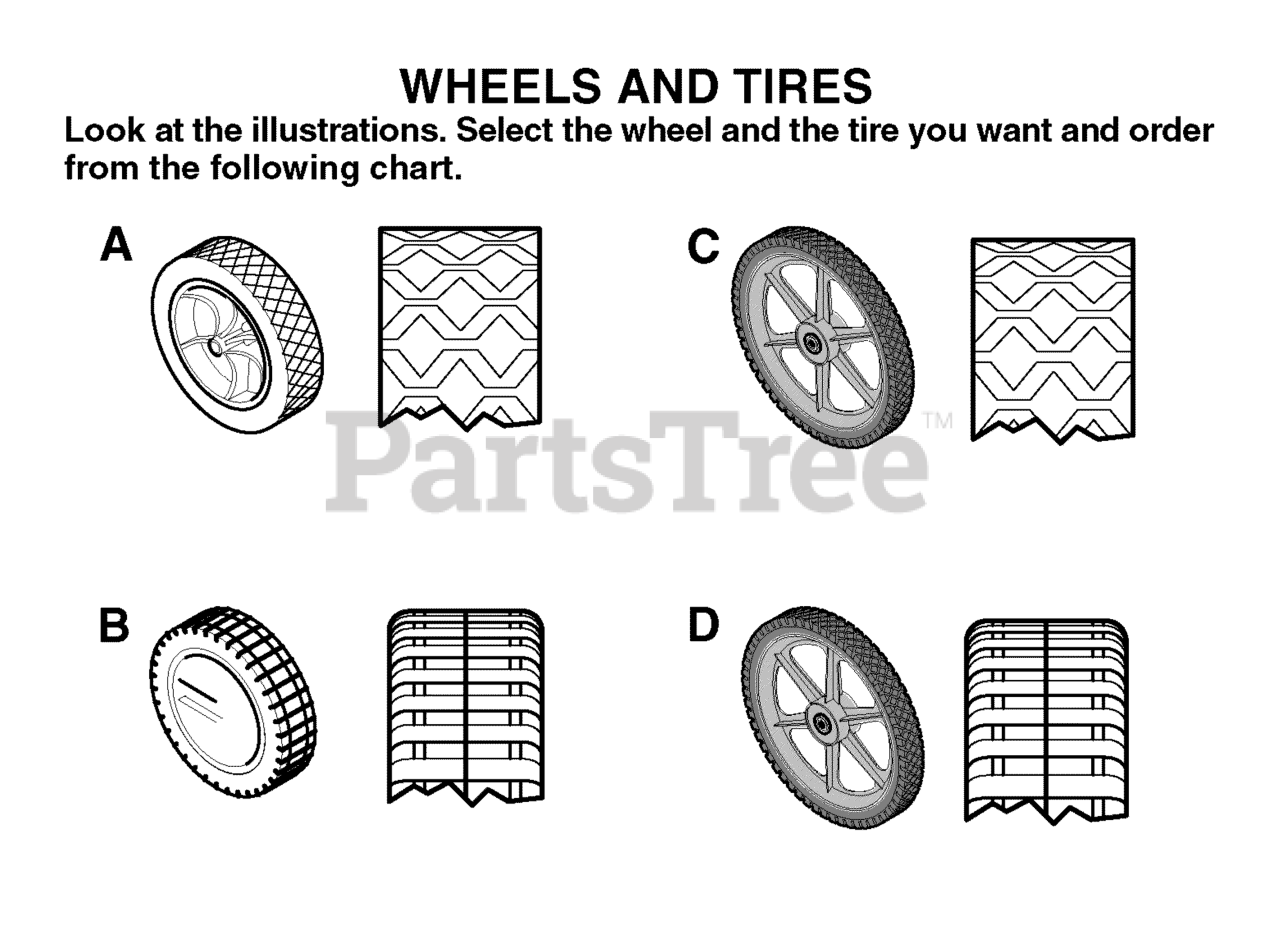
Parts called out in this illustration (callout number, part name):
1	WHEEL & TIRE ASSEMBLY
2	6-inch Plastic, Gray (a)
3	7-inch Plastic, White (a)
4	7-inch Plastic, Gray (a)
5	8-inch Plastic, White (a)
6	8-inch Plastic, Gray (a)
7	8-inch Plastic, Gray (b)
8	8-inch Ball Bearing, Gray (b)
9	14-inch, Gray (c)
10	14-inch, Gray (d)
11	14-in, Ball Bearing, Gray (c)
12	14-in, Ball Bearing, Gray (d)
